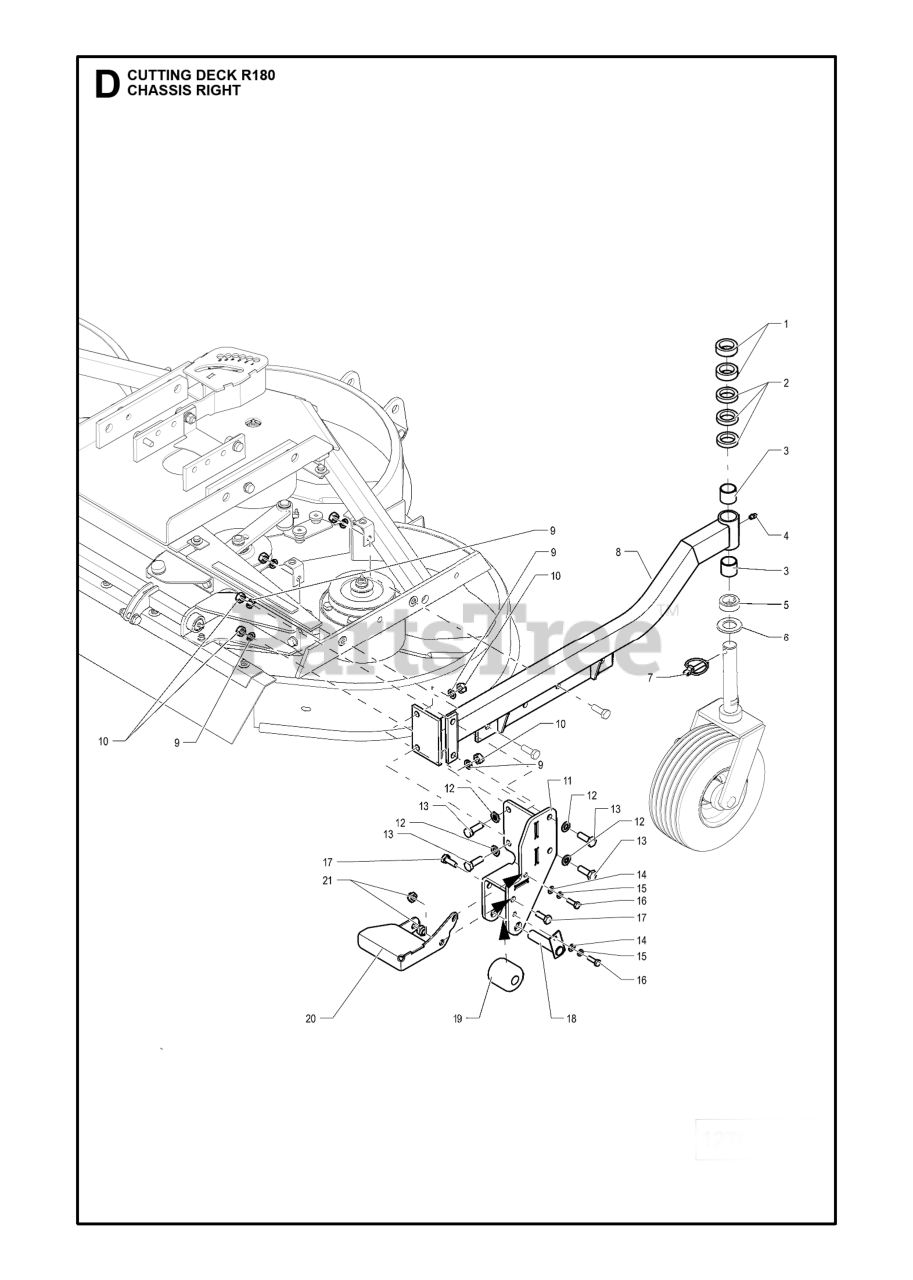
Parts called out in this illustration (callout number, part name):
9	Husqvarna TBD
12	WASHER - M12
16	SCREW M6S 8X25
